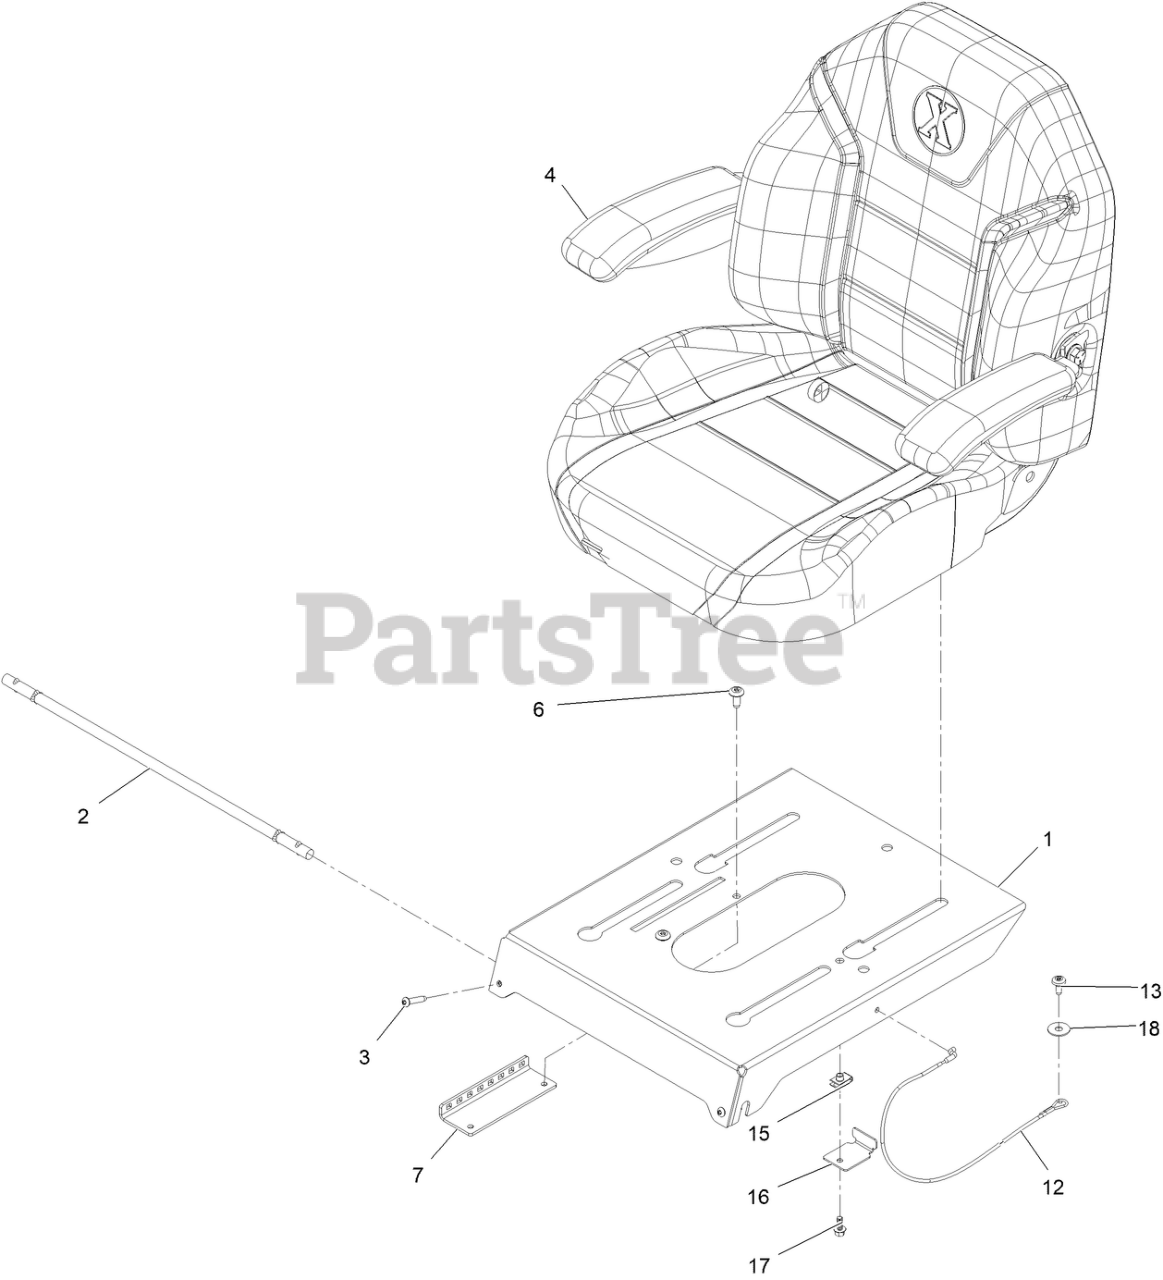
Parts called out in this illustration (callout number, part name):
2	ROD-PIVOT
3	SCREW-TTH, THREAD ROLLING
4	ASM-SEAT EXMARK
7	BRACKET-LATCH, SEAT
12	CABLE-LANYARD
13	SCREW-SHOULDER
16	Bracket-Stop, Seat
17	SCREW-HHF
18	Washer-Flat
